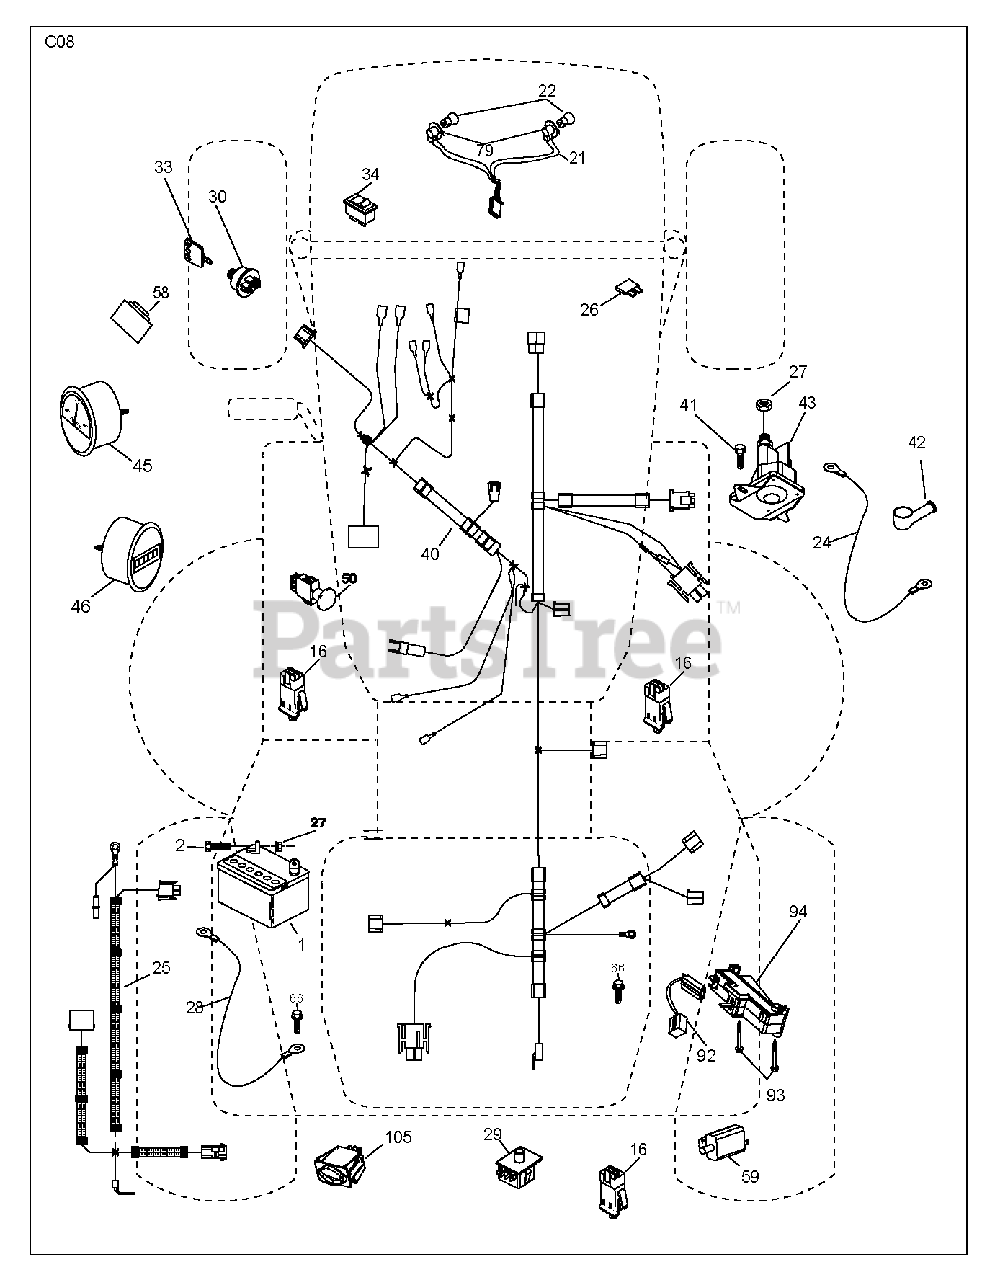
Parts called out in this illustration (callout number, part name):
1	REPL BY 532 12 38-99
16	SWITCH INTERLOOK PUSH-IN
21	HARNESS.W/LIGHT SOCKET
22	LIGHTBULB
25	CABLE BATTERY 6 GA. 11" RED
26	FUSE 20AMP
27	NUT
28	CABLE GROUND
29	SWITCH.SEAT.DP W/RAMPS
30	SWITCH.IGN.DELTA.W.LGH.ROS
33	KEY.CHAIN.BLISTER.PACK.GEN.INT
34	SWITCH LT
42	TERMINAL COVER
43	SOLENOID.W/BRASS.PLUNG
50	PTO SWITCH
58	BUZZER
79	BULB HOLDER ASM.
92	HARNESS.PIGTAIL.CONSLE
93	SCREW.PLASTITE
94	MODULE.REVERSE.ROS
